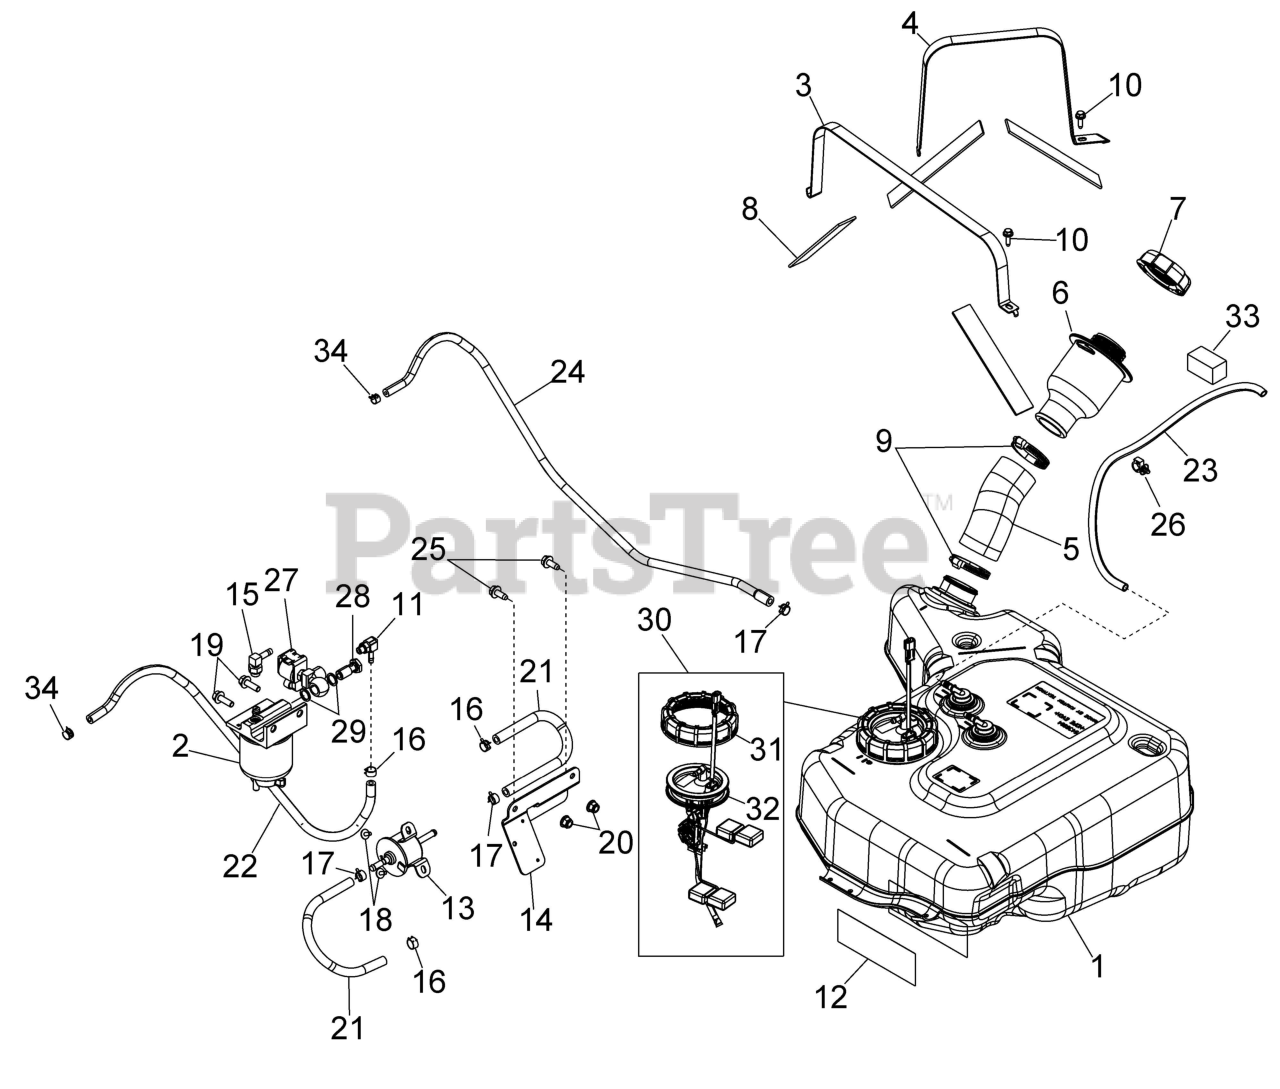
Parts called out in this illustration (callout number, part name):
1	ASM-FUEL TANK,DIESEL
2	ASM., FILTER, FUEL
3	BRKT-TANK,STRAP,INSIDE,GALV
4	BRKT-TANK,STRAP,OUTSIDE,GALV
5	HOSE-FUEL FILL
6	ASM-FUEL INLET
7	CAP-TANK,DIESEL
7	CAP, FUEL TANK DIESEL
8	PAD, BATTERY
9	CLAMP,BAND,NARROW (10)
10	SCR-M6X1.0X20,HXHD,FLG,TDFM,BL
11	FITTING-M10X1.0X6.35-90
12	FOIL-FENDER JOINT,RH
13	ASM., FUEL PUMP
14	BRKT-FUEL SYSTEM MOUNT
15	FITTING-SAEJ1926-1/2-20X.25-90
16	CLAMP,HOSE(10)
17	CLAMP-HOSE, 17/32, GREEN
18	SCREW(10)
19	BOLT-M8X1.25X25,HXFLG-OLIVE D
20	NUT-M8X1.25,FLG,NYLOC-OLIVE D
21	HOSE, FUEL-25 CM
22	HOSE, FUEL
23	FUEL LINE-50 CM
24	HOSE-FUEL,3/16 ID,5/16 FLARE
25	BOLT-M8X1.25X20,HXFLG,TAP/R-OD
26	CLIP,ROUTING,.472 B.D.,HINGED
27	SOLENOID, FUEL
28	BOLT, BANJO
29	WASHER, COPPER
30	KIT-FUEL SENDER,DIESEL
31	NUT, JAM
33	FILTER-VENT LINE
34	CLAMP-HOSE
